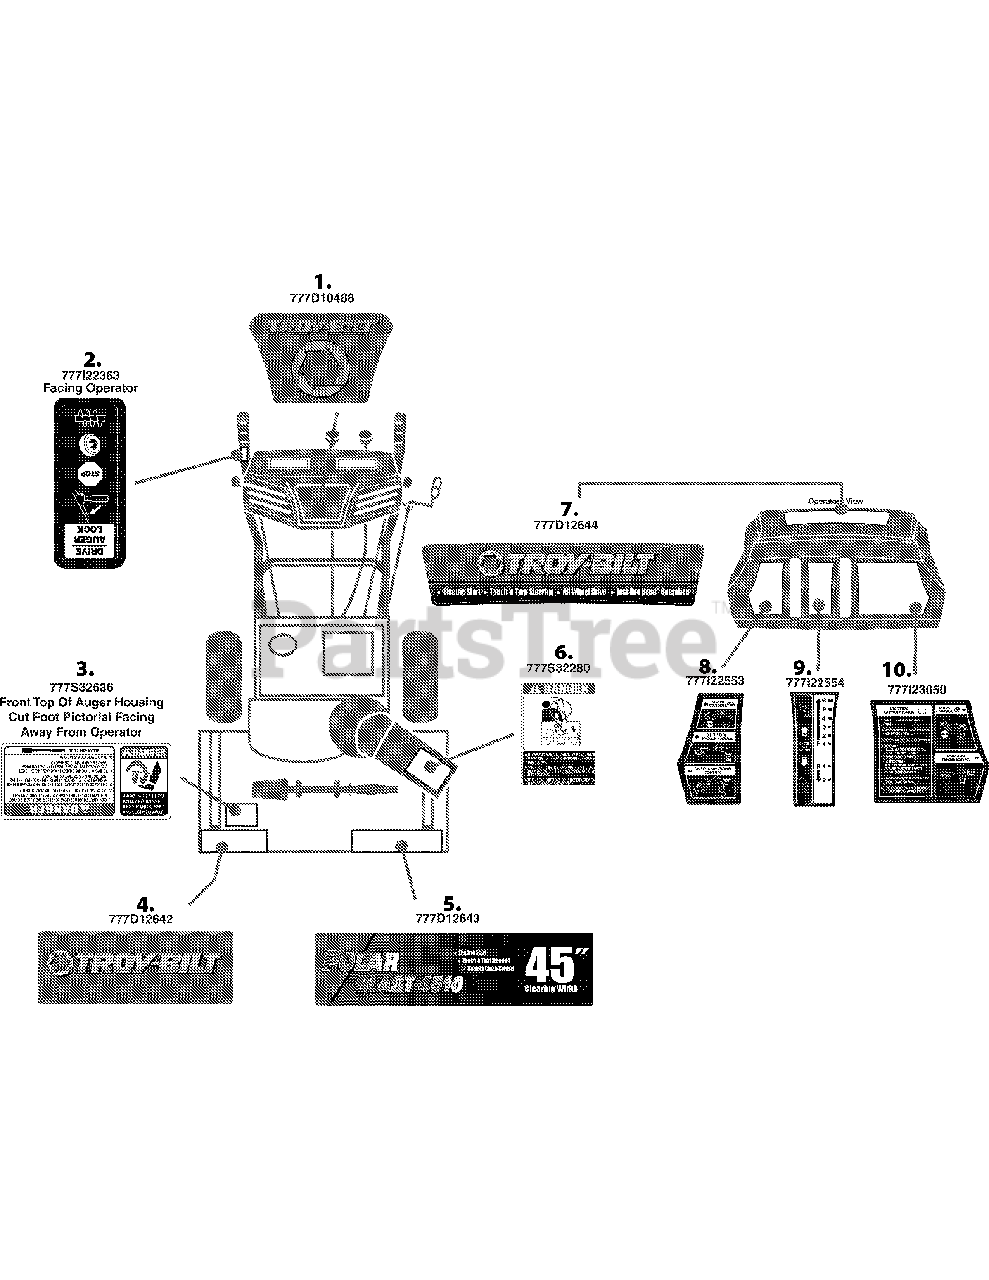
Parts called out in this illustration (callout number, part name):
1	LABEL-SNOW HANDLE:FRONT TROY
2	LABEL-DRV/AUGR LOCK
3	LABEL-SNOW HOUSING
4	LABEL-SNOW FRONT LH AUGER TB
5	LABEL-SNOW FRONT RH TROY
6	LABEL-CHUTE
7	LABEL-SNOW HANDLE PANEL TROY
8	LABEL-CNTRL PNL LH
9	LABEL-CNTRL PNL CN
10	LABEL-SNW:7 PNL:ST INSTR:B&S
